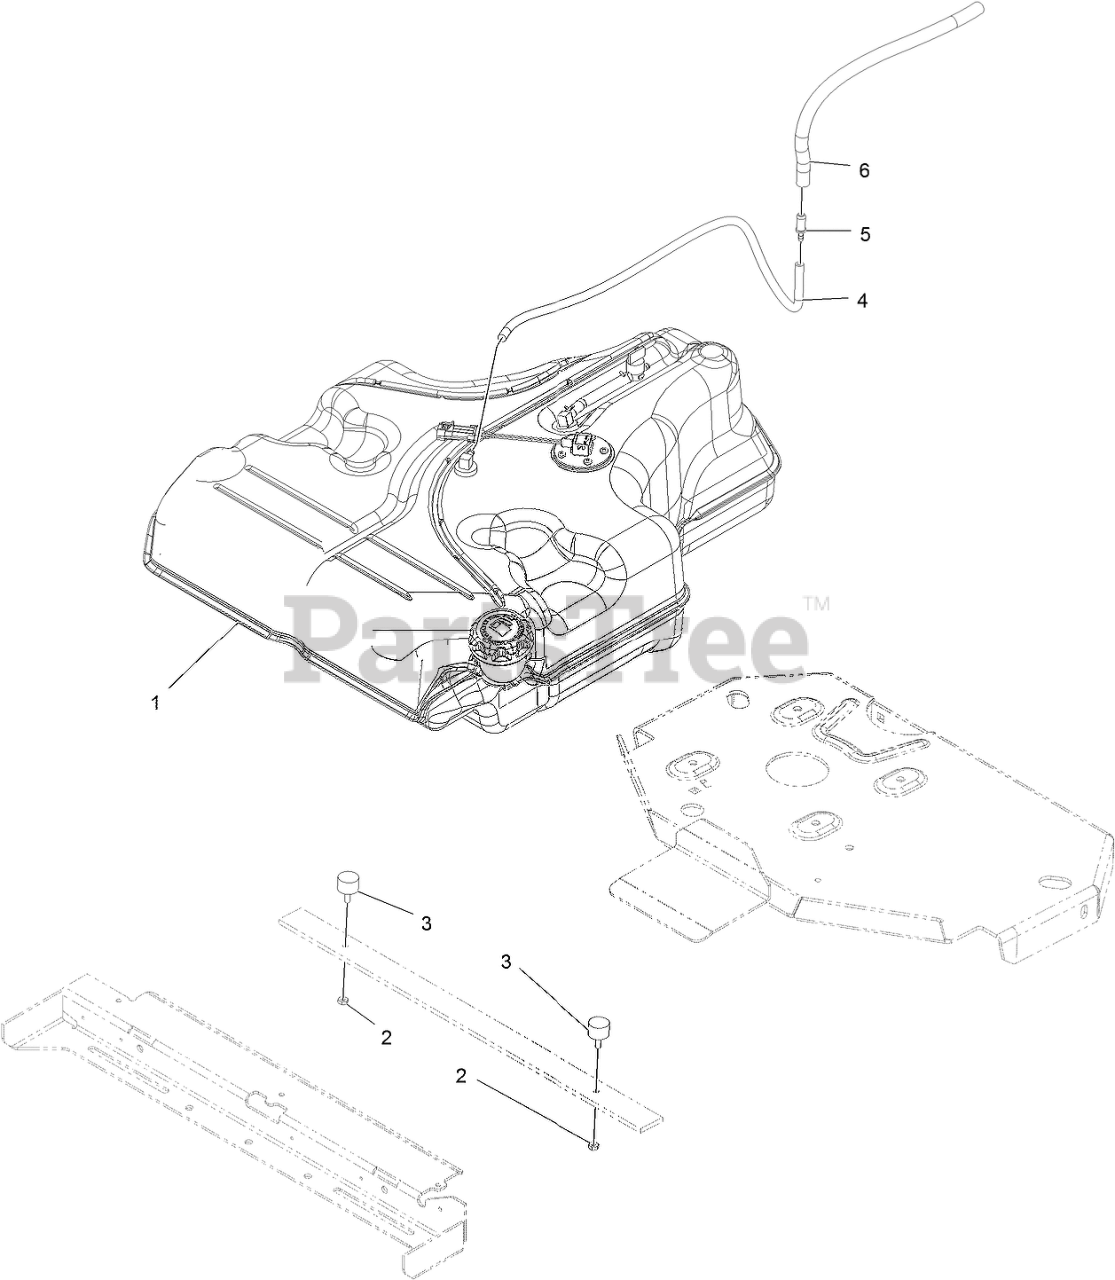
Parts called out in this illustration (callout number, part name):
1	FUEL TANK ASM
2	NUT-JAM
4	HOSE-FUEL
5	FITTING-STRAIGHT
6	HOSE-FUEL
